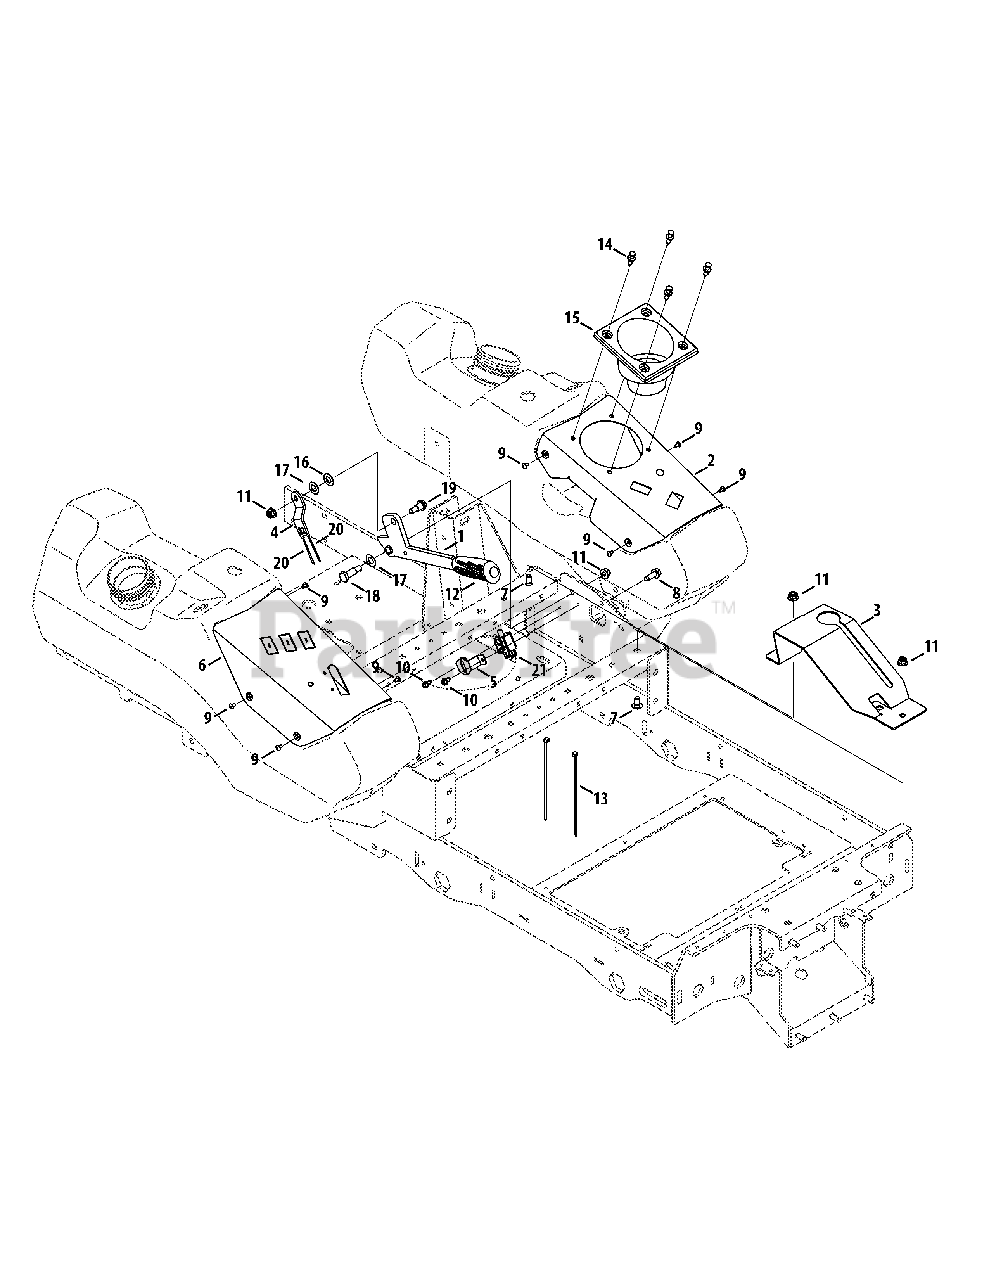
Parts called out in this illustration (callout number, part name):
1	Brake Handle Weldment
2	LH Control Panel
3	Boot Brake Bracket
4	Pivot Brake Bracket
5	Brake Switch Bracket
6	RH Control Panel
7	Carriage Bolt, 3/8-16 x .75
8	Screw, 3/8-16 x 1.00
9	Machine Screw, #10-32 x .25
10	Hex Flange Screw, 1/4-20 x .500
11	Nut, 3/8-16, Flangelock
12	Grip, .50 ID
13	Cable Tie
14	Rivet, .3125
15	Cup Holder
16	Washer, .510 x 1.00 x .060
17	Washer, .531 x 1.00 x .030
18	Shoulder Bolt, .50 x .925, 3/8-16
19	Shoulder Screw, .50 x .50, 3/8-16
20	Brake Cable
21	Switch, NC/NO/NO
